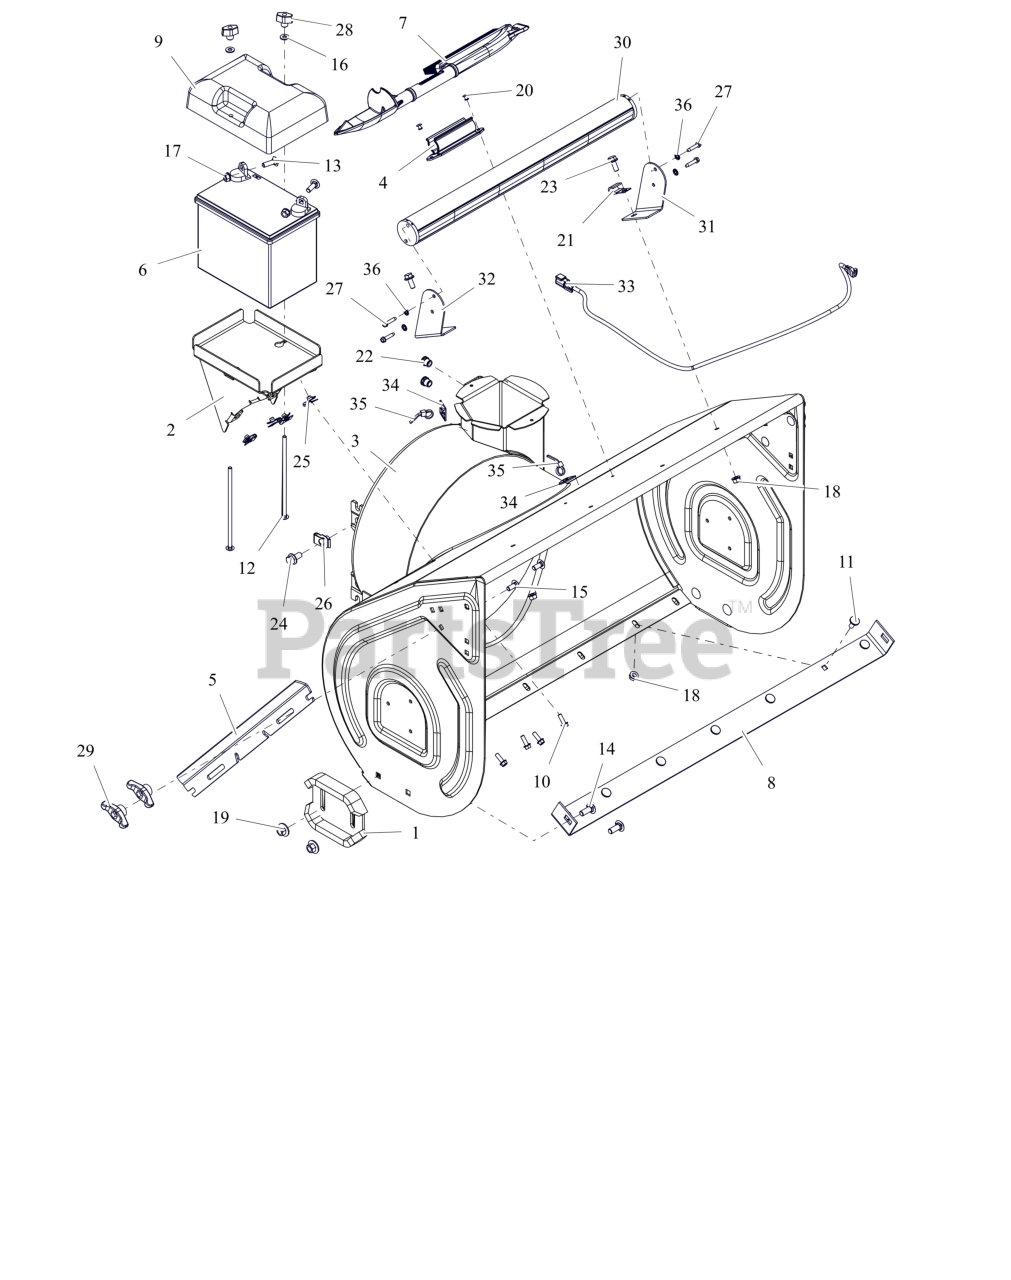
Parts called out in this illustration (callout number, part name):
1	RUNNER, SKID SHOE
2	TRAY, BATTERY
3	HOUSING, BLOWER 32" W/DECAL
4	MOUNT, SNOW CLEAN OUT
5	CUTTER, DRIFT
7	DEVICE, SNOW CLEAN OUT W/BRUSH
8	BLADE, SCRAPER-32"
9	COVER, BATTERY
10	BLT, HWH .25-20X.75 G5 ZCC
11	BOLT, MODIFIED HEAD CARRIAGE
12	BLT,RHSN .25-20X7.00 G2 ZCC
13	BLT,RHSN .31-18X1.00 G5 ZCC
14	BLT,RHSSN .38-16X1.00 G5 ZCC
15	BLT, RHSSN.31-18X.750 G5 ZCC
16	WSHR,FLT .281X.625X.065 ZCC
17	NUT,LK-CTR-FLG .31-18 GF ZCC
18	NUT-LK-TOP-FLG .312-18 GF ZCC
19	NUT- CON-LN .375-16 ZC120
20	RVT, POP .1875 ZCC
21	J-CLAMP
22	NUT,THD,INSERT .38-16 ZC120
23	BLT- SERHFWH .312-18X.75 ZCC
25	NUT-RTNR .25-20X.56
26	NUT-RTNR .375-16X.37
27	@SCR-TAP 12-24X1.00 HWH TR CZ
28	KNOB, WING - .25-20 UNC
29	KNOB,WING .31-18 UNC NYL/TALC
30	LIGHT, HOUSING - LED LIGHTBAR
31	BRKT-HOUSING LIGHT - LED LH
32	BRKT- HOUSING LIGHT - LED RH
33	HARNESS- WIRE - LG ACC LT
34	MOUNT, CABLE-TIE DOWN
35	CABLE TIE LG 5-1/2
36	WSHR-LK-EXT 12X.025 PL
